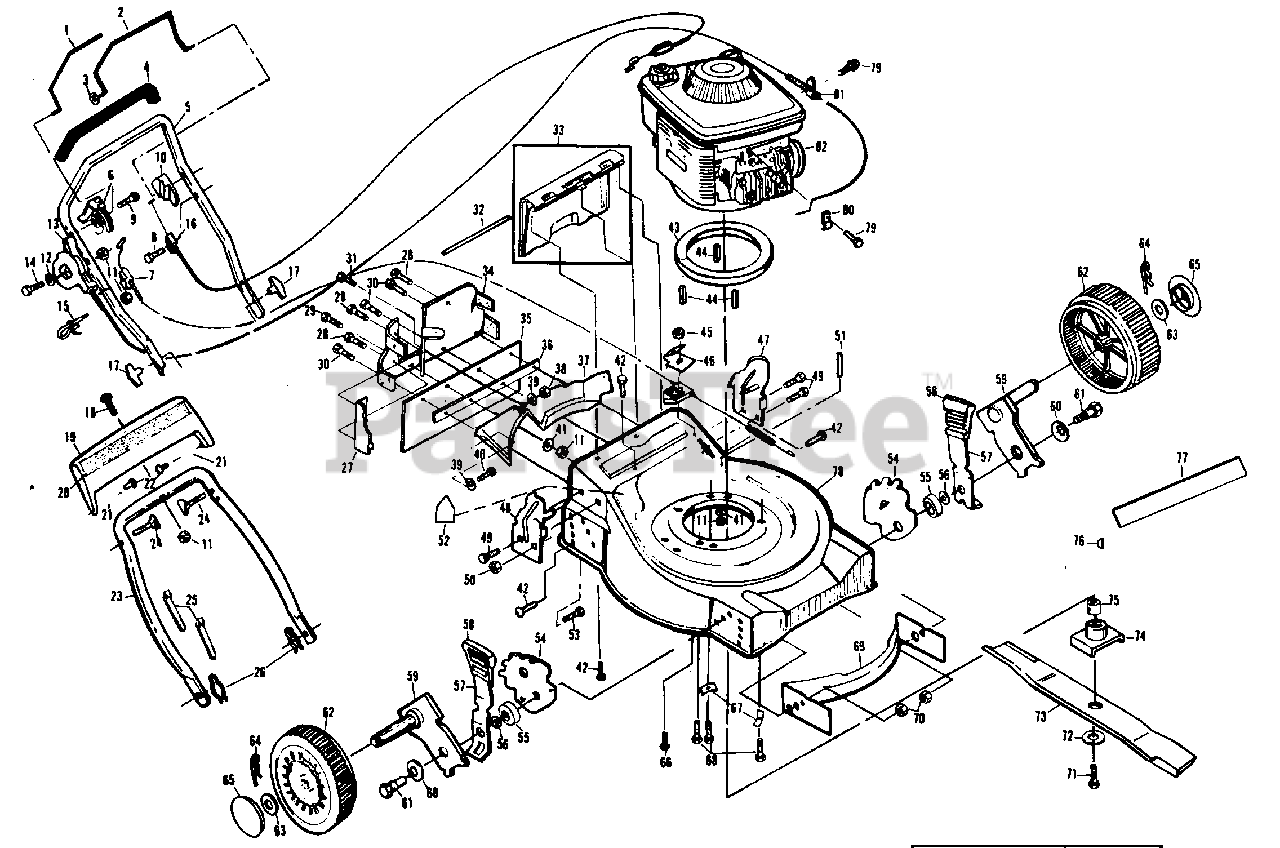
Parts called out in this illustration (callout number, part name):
1	Drive Bar
2	Engine Control Bar (AYP part number)
3	Flat Washer (AYP part number)
4	Handle Grip (AYP part number)
5	Upper Handle
6	Drive Control Actuator (AYP part number)
7	Drive Cable Assembly
8	Hex Thread Rolling Screw (AYP part number)
9	Self Tapping Screw (AYP part number)
10	Zone Control Actuator (AYP part number)
11	Locknut (AYP part number)
12	Flat Washer (AYP part number)
13	Throttle Control (AYP part number)
14	Machine Screw (AYP part number)
15	Rope Guide (AYP part number)
16	Engine Control Cable Assembly (AYP part number)
17	Handle Knob (AYP part number)
18	Hex Washer Head Machine (AYP part number)
19	Trim Plate
20	Trim Plate Decal 4.0 HP (AYP part number)
21	Nylon Bushing (AYP part number)
22	Tapping Screw (AYP part number)
23	Lower Handle (AYP part number)
24	Handle Bolt
25	Wire Tie (AYP part number)
26	Hairpin Cotter (AYP part number)
27	Side Baffle (AYP part number)
28	Self Tapping Screw (AYP part number)
29	Hex Head Screw (AYP part number)
30	Hex Tapping Screw (AYP part number)
31	Hex Washer Head Machine Screw (AYP part number)
32	Hinge Rod (AYP part number)
33	Rear Door Kit (AYP part number)
34	Back Plate
35	Rear Skirt (AYP part number)
36	Backing Strip (AYP part number)
37	Rear Baffle
38	Locknut (AYP part number)
39	Flat Washer (AYP part number)
40	Hex Washer Head Tapping Screw (AYP part number)
41	Washer (AYP part number)
42	Hex Tapping Screw (AYP part number)
43	Engine Spacer (AYP part number)
44	Engine Bushing (AYP part number)
45	Keps Nut (AYP part number)
46	Bracket Cover (AYP part number)
47	Handle Bracket Assembly (Left)
48	Handle Bracket Assembly (Right) (AYP part number)
49	Thread Cutting Screw (AYP part number)
50	Locknut (AYP part number)
51	Carriage Bolt (AYP part number)
52	Danger Decal (AYP part number)
53	Carriage Bolt (AYP part number)
54	Wheel Adjusting Bracket (AYP part number)
55	Spacer (AYP part number)
56	Flat Washer (AYP part number)
57	Selector Spring (AYP part number)
58	Selector Knob (AYP part number)
59	Axle Arm Assembly (AYP part number)
60	Belleville Washer (AYP part number)
61	Shoulder Bolt (AYP part number)
62	Wheel & Tire Assembly (AYP part number)
63	Flat Washer (AYP part number)
64	Retainer Clip (AYP part number)
65	Hubcap (AYP part number)
66	Machine Screw (AYP part number)
67	Engine Washer (AYP part number)
68	Hex Head Thread Rolling Screw (AYP part number)
69	Front Baffle (AYP part number)
70	Locknut (AYP part number)
71	Hex Head Machine Screw Grd. 8 (AYP part number)
72	Helical Lockwasher (AYP part number)
73	Blade 22" (AYP part number)
74	Blade Adpater (AYP part number)
75	Spacer (AYP part number)
76	Hi-Pro Key #HP 505 (AYP part number)
77	Housing Front Decal (AYP part number)
78	Lawn Mower Housing (AYP part number)
79	Thread Rolling Screw (AYP part number)
80	Cable Clamp (AYP part number)
81	Cable Clip (AYP part number)
